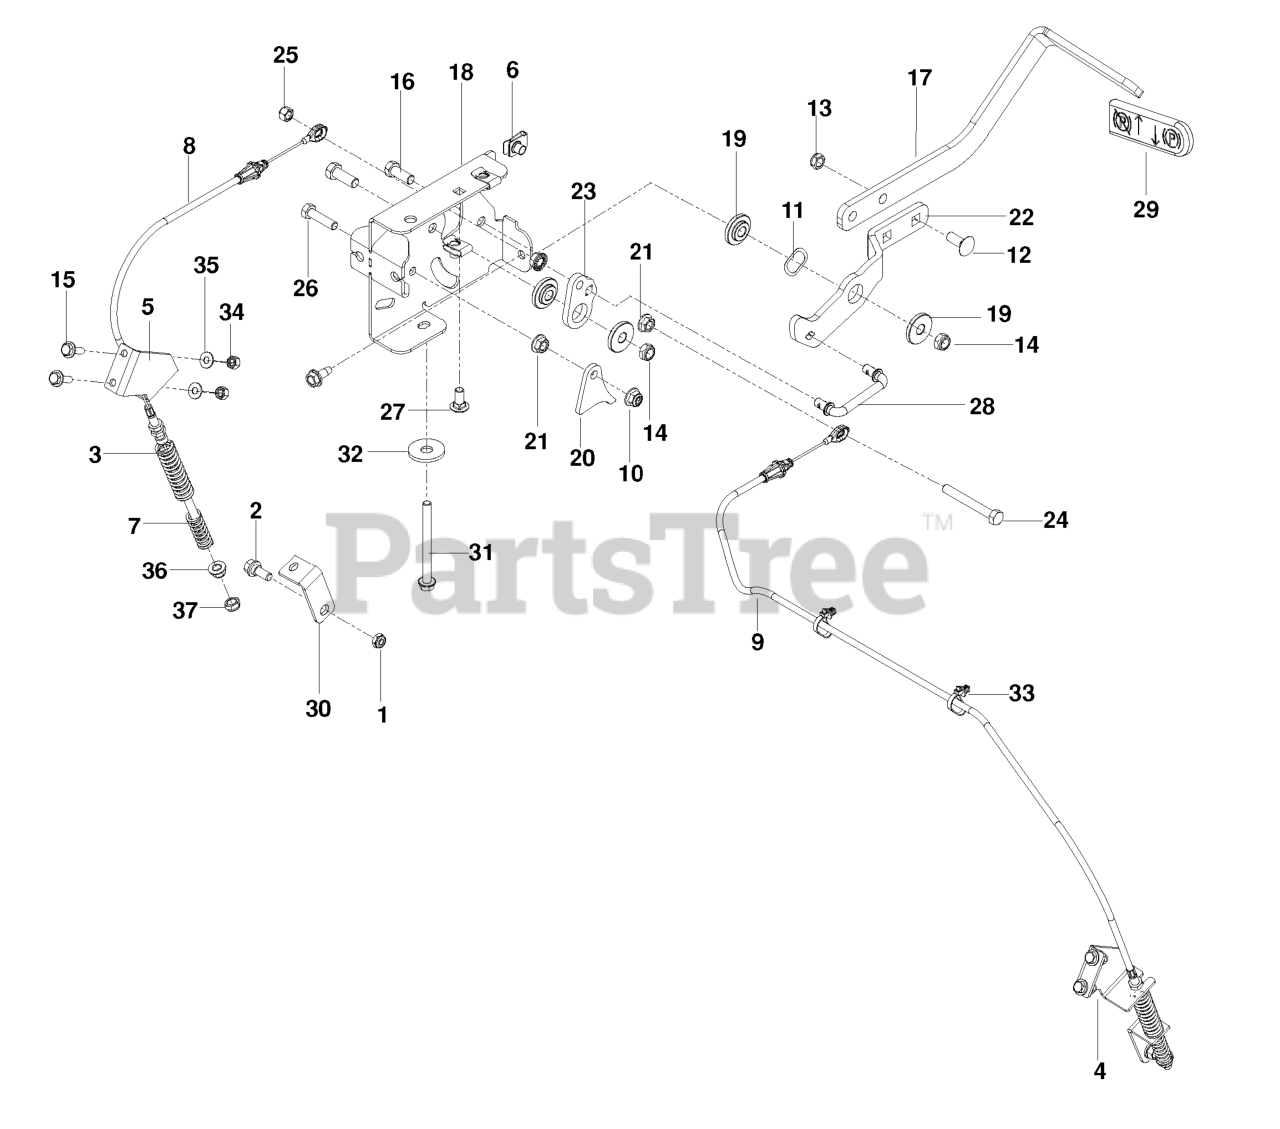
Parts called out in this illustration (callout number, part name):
1	5/16-18 THIN PROF NY
2	BOLT, SHOULDER
3	SPRING, RETURN
4	BRKT, BRAKE RT, BLK
5	BRKT, BRAKE LT, BLK
6	U-CLIP 5/16-18 NUT RETAINER
7	SPRING, ENGAGEMENT
8	CABLE, BRAKE, SHORT
9	RP_CABLE, BRAKE, LONG
10	5/16-18 NYLOC FLANGE NUT
11	WASHER, .825 X 1.087, WAVE
12	RHSNB 3/8C X 1
13	NUT 3/8-16 HEX FLG NYLOC ZD
14	NUT HEX 3/8-16 NYLON, THIN
15	HCS 1/4-20X7/8 GR5
16	HCS 3/8-16X1.GRD.5.ZD
17	ARM, BRAKE
18	MOUNT, BRAKE WLDMT
19	BUSHING, BRAKE
20	ACTUATOR, SWITCH
21	NUT 5/16C WHIZ
22	LEVER, BRAKE
23	BELLCRANK, BRAKE
24	HCS 5/16-18 X 2 1/2 TPBLT
25	NUT 5/16 NYLOC
26	HCS 5/16C X 1
27	BOLT 5/16C X 3/4" CARRIAGE
28	LINKAGE, BRAKE
29	GRIP, PARK BRAKE
30	BRKT, BRAKE, BLK
31	HHFS 5/16-18 X 3 3/4
32	WASH USS FLAT 1/2
33	TIE WRAP, 8-3/8", W/CLIP
34	NUT.1/4-20.HEX.NYLOC.ZD
35	WASHER 1/4 SAE
36	NUT 5/16C WHIZ
37	NUT 5/16-18 HEX JAM ZD
